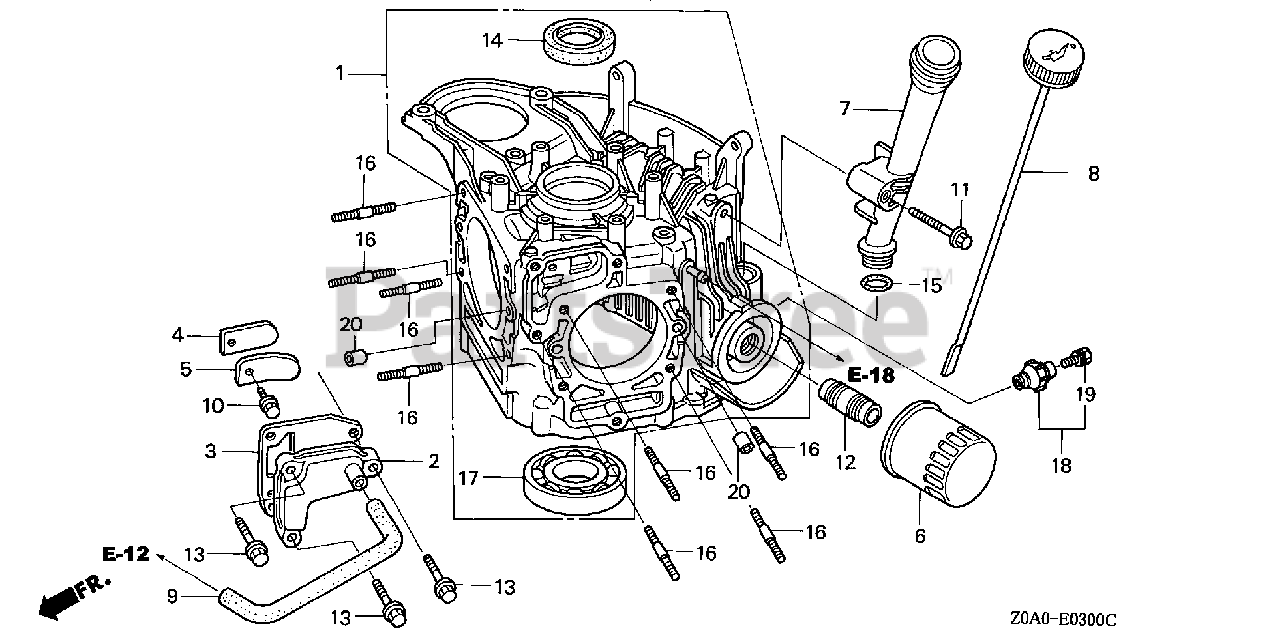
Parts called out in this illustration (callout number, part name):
1	CRANKCASE ASSY.
2	COVER, BREATHER
3	GASKET, BREATHER COVER
4	PLATE, VALVE
5	STOPPER, VALVE
6	FILTER, OIL (TOYO ROKI)
7	EXTENSION, OIL FILLER
8	GAUGE, OIL LEVEL
9	TUBE, BREATHER
10	BOLT, FLANGE (5X10)
11	BOLT, FLANGE (6X45) (CT200)
12	HOLDER, OIL FILTER
13	BOLT, FLANGE (6X25) (CT200)
14	OIL SEAL (35X52X8)
15	O-RING (22.1X2.2)
16	BOLT, STUD (8X28)
17	BEARING, RADIAL BALL (6207)
18	SWITCH ASSY., OIL PRESSURE
19	BOLT-WASHER (4X8) (DENSO)
20	PIN, DOWEL (8X14)
